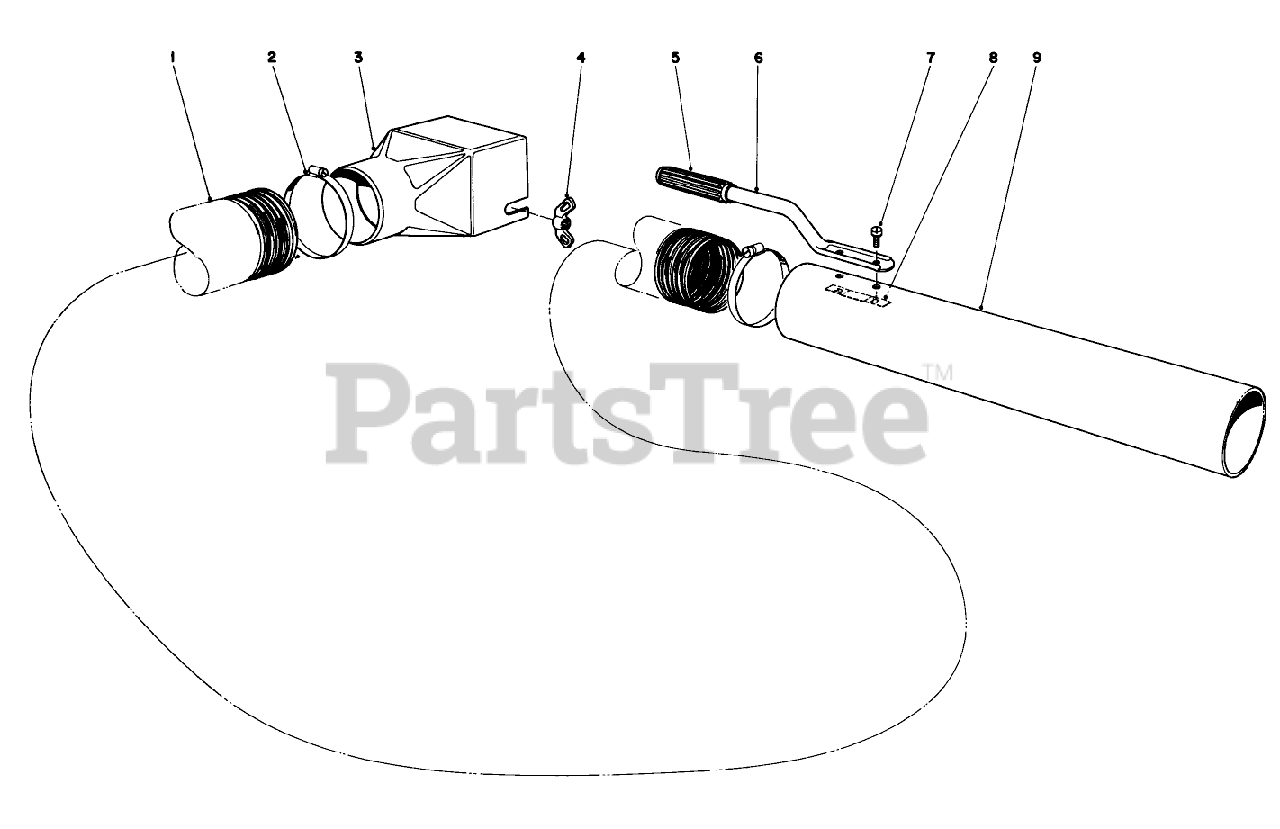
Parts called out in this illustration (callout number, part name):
2	Clamp
3	Hose Adaptor
4	Wing Nut
6	Handle
8	Special Nut
9	Nozzle
